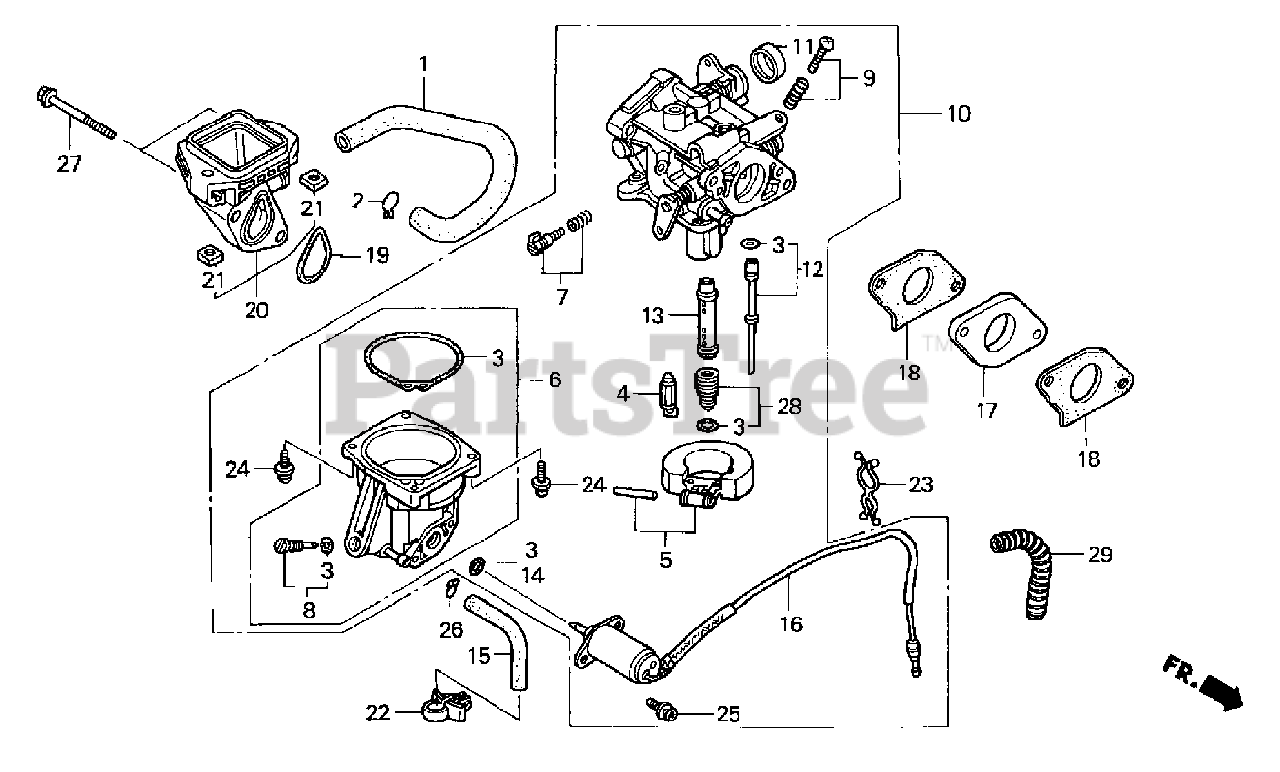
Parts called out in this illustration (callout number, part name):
1	Tube, Breather
2	Clip, Breather Tube
3	Gasket Set
4	Valve Set, Float
6	Chamber Set, Float
8	Screw Set, Drain
10	Carburetor Assembly. (Bg22g A)
11	Cap, Choke Lever Dust
12	Jet Set (#52)
14	O-ring (5.8x1.9)
15	Tube, Drain
16	Valve Assembly., Solenoid
17	Insulator, Carburetor
18	Gasket, Carburetor
19	Gasket, Air Cleaner
20	Elbow, Air Cleaner
21	Nut, Insert (6mm)
22	Clip B, Cable
23	Clip, Purse Lock
24	Screw-washer (4x14)
25	Screw-washer (5x12)
26	Clip, Tube (B8)
27	Bolt, Flange (6x120)
28	Jet Set, Main (#110)
